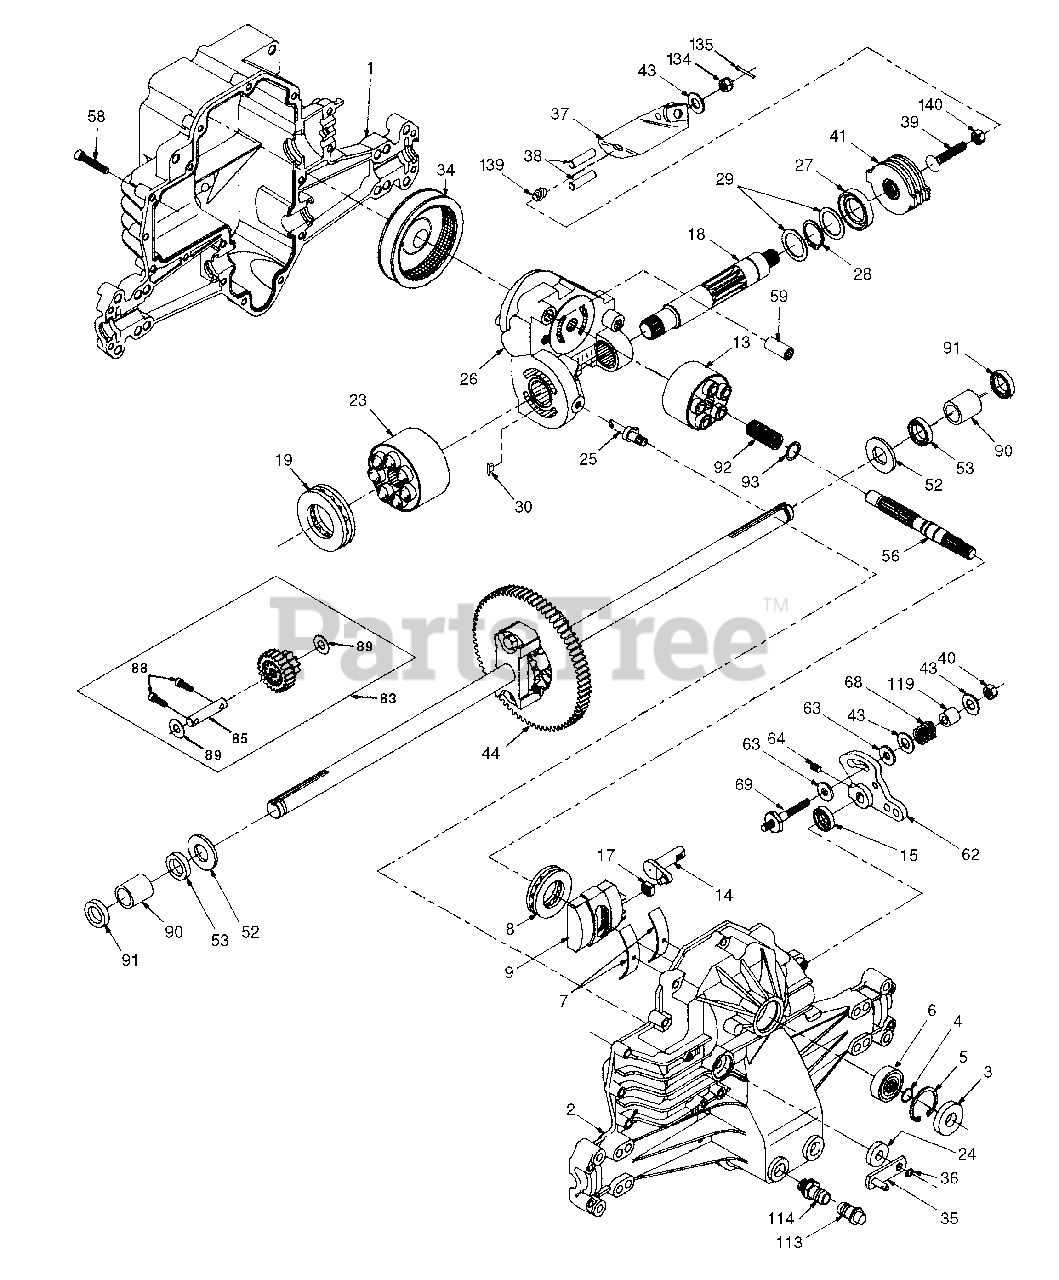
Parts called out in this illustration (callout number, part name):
1	Housing, Lower
2	Assembly, Upper Housing
4	Ring, Wire Retaining
5	Ring, Retaining
6	Bearing, Shaft Ball
7	Bearing, Cradle
8	Bearing, Thrust 30 x 52 x 13
9	Swashplate, Variable
13	Block, Cylinder Assembly
14	Arm, Trunnion
17	Guide, Slot
18	Shaft, Motor
19	Bearing, Thrust 42 x 68 x 16
23	Block, Cylinder Assembly
24	Seal, Lip 10 x 25 x 7
25	Actuator, Bypass
26	Center Section Assembly Kit
27	Seal, Lip 26 x 42 x 8
28	Ring, Retaining
29	Washer 26 x 35 x 1
30	Plate, Bypass
34	Oil Filter Element
35	Arm, Bypass
36	Ring, Retaining
37	Arm, Actuating
38	Pin, Actuating
39	Bolt 5/16-24 x 1-3/4
40	Locknut, Hex 5/16-24 UNJC
41	Brake Rotor/Stator Kit
43	Washer 7/16 x 7/8 x .060
44	Differential Assembly
52	Washer 3/4 x 1.5 x .13
53	Seal .75 x 1.25 x .250
56	Shaft, Input
58	Bolt 1/4-20 x 1.38
59	Pin .5 OD x .43 ID x .750
62	Arm, Control
63	Puck, Dampener
69	Stud 5/16-24
83	Jackshaft Assembly
88	Screw, Cap
89	Washer 7/16 x 1 x 1/2
90	Sleeve Bearing
91	Seal, Wiper
92	Spring, Block
93	Washer, Block Thrust
113	Cap, Vent Assembly
114	Fitting, O-Ring Assembly
119	Spacer
134	Nut, Castle 5/16-24
135	Pin, Cotter
139	Spring, Compression
140	Nut, Hex 5/16-24
